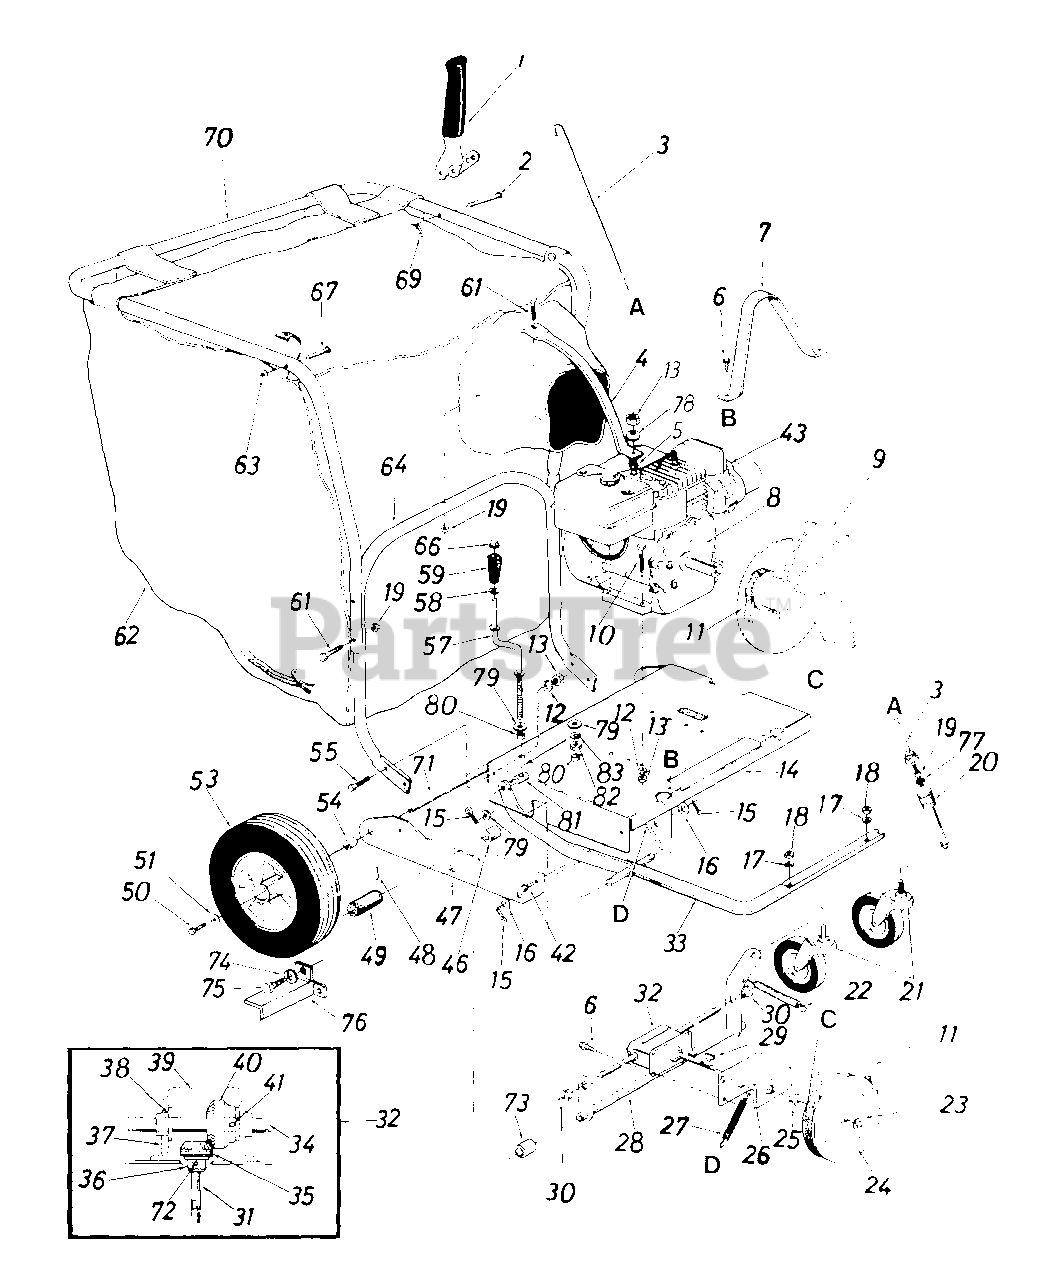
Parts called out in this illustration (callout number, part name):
1	Clutch Grip Ass'y.
2	Clevis Pin .375" Dia. x 1.88"
3	Clutch Rod 32" Lg.
4	Handle Brace (Painted)
5	Part of Engine
6	Hex Wash. Hd. AB-Tap Scr. 1/4" x .62" Lg.
9	Air Vane Plate Ass'y. w/Pulley
10	Hex Bolt 5/16-18 x 1.5" Lg.
11	V-Belt
12	L-Wash. 5/16" I.D.
13	Hex Nut 5/16-18 Thd.
16	Fl-Wash. .63" I.D. x 1.25" O.D.
17	L-Wash. 1/2" I.D.
18	Hex Nut 1/2-13 Thd.
19	Hex Cent. L-Nut 1/4-20 Thd.
20	Extension Spring .78" O.D. x .75" Lg.
21	Swivel Caster Wheel 5" Dia. x 1.25"
22	Extension Spring .38" O.D. x 7.50" Lg.
23	Snap "E"-Ring .50" Dia. Shaft
24	V-Pulley 5/8" x 6.50" O.D.
25	Flange Bearing .502" I.D.
28	Clutch Bracket Ass'y.
29	#2 Woodruff Key 3/32" Dia. x .81" Lg.
30	Hex Flange Bearing Bronze .625" I.D.
31	Pinion Shaft .50" Dia. x 5"
32	Gear Box Ass'y. Comp.
35	Bevel Gear .50" I.D. x 14 Teeth
36	Flange Bearing .503" I.D.
37	Gear Box
38	Flange Bearing .630" I.D.
39	Gear Box Cover
40	Bevel Gear .62" I.D. x 28 Teeth
41	Spring Pin Spiral 3/16" Dia. x 1.25" Lg.
42	Hex Wash. Hd. AB-Tap Scr. 5/16" x .75" Lg.
43	Engine
43	Muffler Guard Ass'y.
46	Spacer .63" I.D. x .88" O.D. x .56" Lg.
49	Drive Pinion
50	Hex Locking Bolt 5/16-24 x .62" Lg.
51	Fl-Wash. .34" I.D. x .87" O.D.
53	Wheel Ass'y. Comp. 12" x 3"
54	Spacer .63" I.D. x 1.0" O.D. x .94" Lg.
55	Hex Bolt 5/16-18 x .75" Lg.
57	Height Adjustment Crank
58	Fl-Wash. .385" I.D. x .62" O.D.
59	Crank Knob
61	Hex Bolt 1/4-20 x 1.75" Lg.
62	Vacuum Bag - Felt
63	Push Speed Nut .25" Dia. Stud
67	Stud Pin .250" Dia. x 1.75"
69	Internal Cotter Pin 3/8" Dia.
70	Upper Handle (Painted)
71	Rear Axle
72	Spring Roll Pin 5/32" Dia. x 1.12
73	Spacer .82" I.D. x 1.0" O.D. x .305 Lg.
74	L-Wash. .265" I.D.
75	Hex Self-Tap Scr. 1/4" x 3/8" Lg.
78	Belleville Washer
79	Fl-Wash. .35" I.D. x .87" O.D.
80	Spacer .38" I.D. x .50" O.D. x .18" Lg.
81	Ferrule 3/8-8 x .38" Dia.
82	Hex Nut 3/8-8 Thd.
83	L-Wash. 3/8" I.D.
